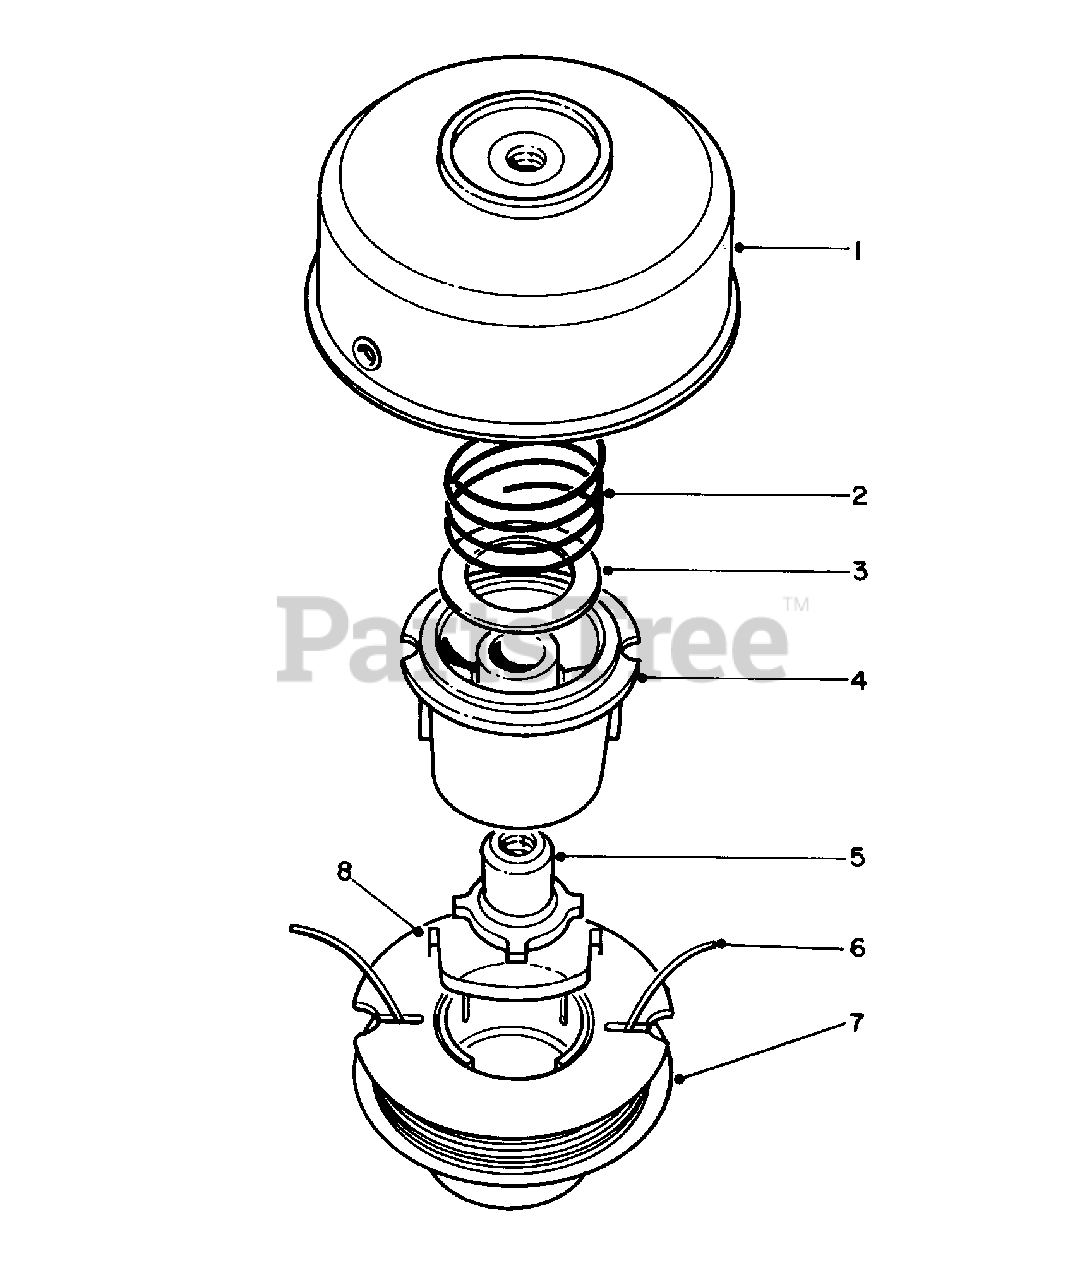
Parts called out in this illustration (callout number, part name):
1	Drum Assembly w/Eyelets
4	Spool Core
5	Driver L.H.
6	.080 Filament Line in Coil (38ft.)
7	Prewound Spool
8	Saddle-Spool Cap
